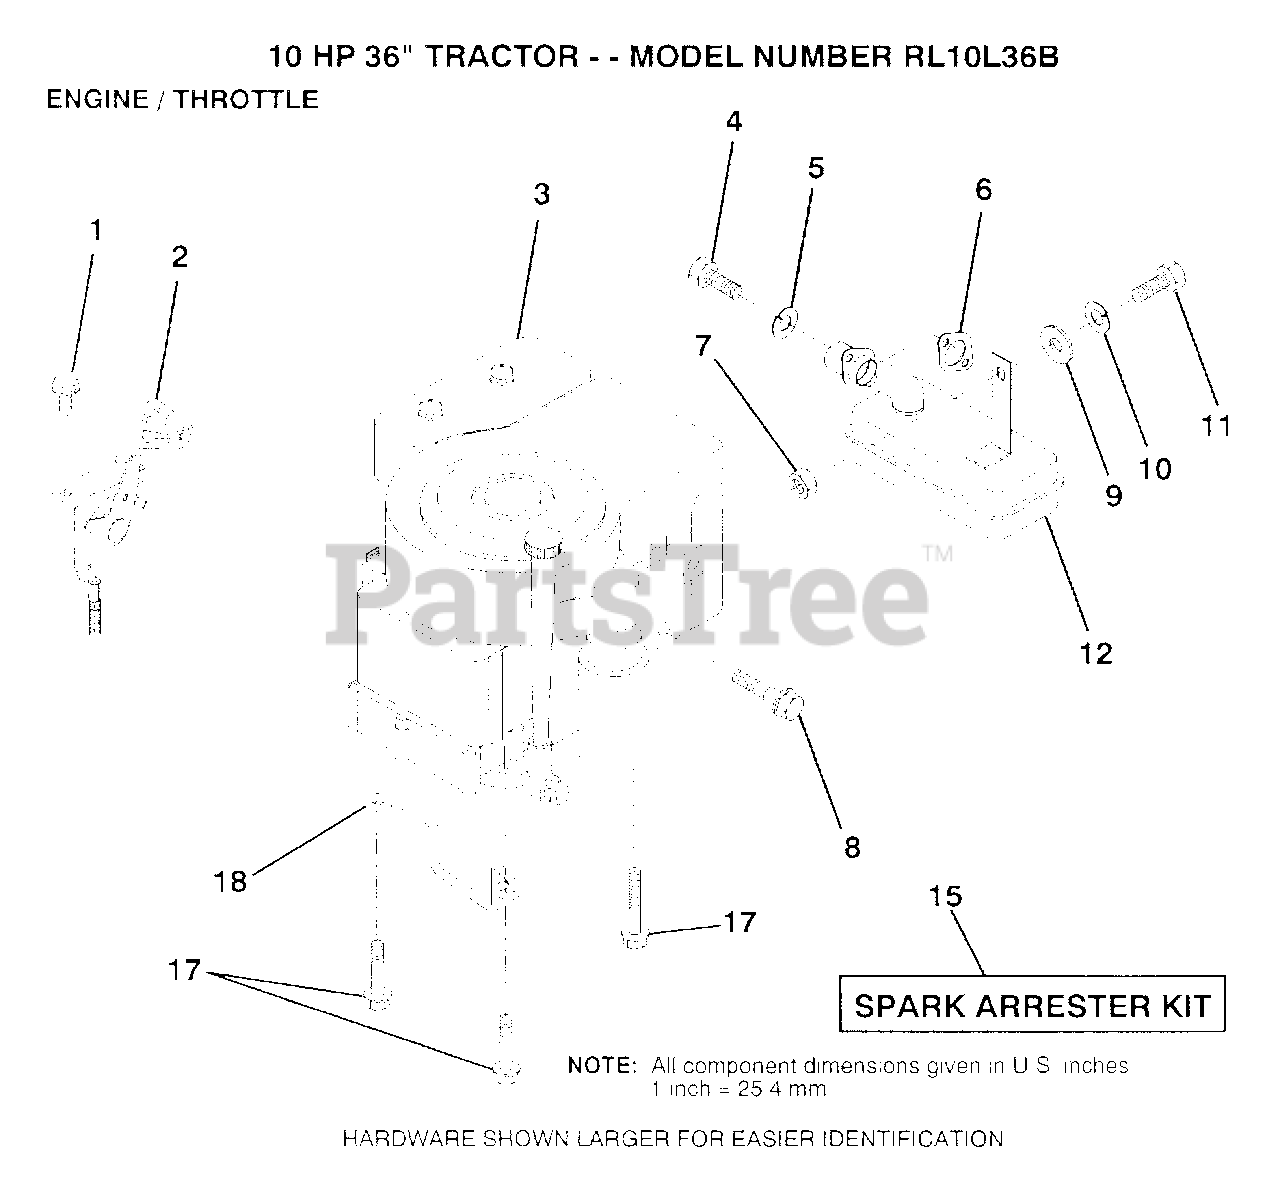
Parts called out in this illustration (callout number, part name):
1	SCREW.1/4-20X1/2
2	"CONTROL,THROTTLE"
4	SCREW
5	LOCKWASHER
7	NUT.HEX.5/16-18
8	BOLT T
10	LOCKWASHER
11	BOLT
12	MUFFLER
17	SCREW LT
18	"KEEPER,DR BELT GR"
